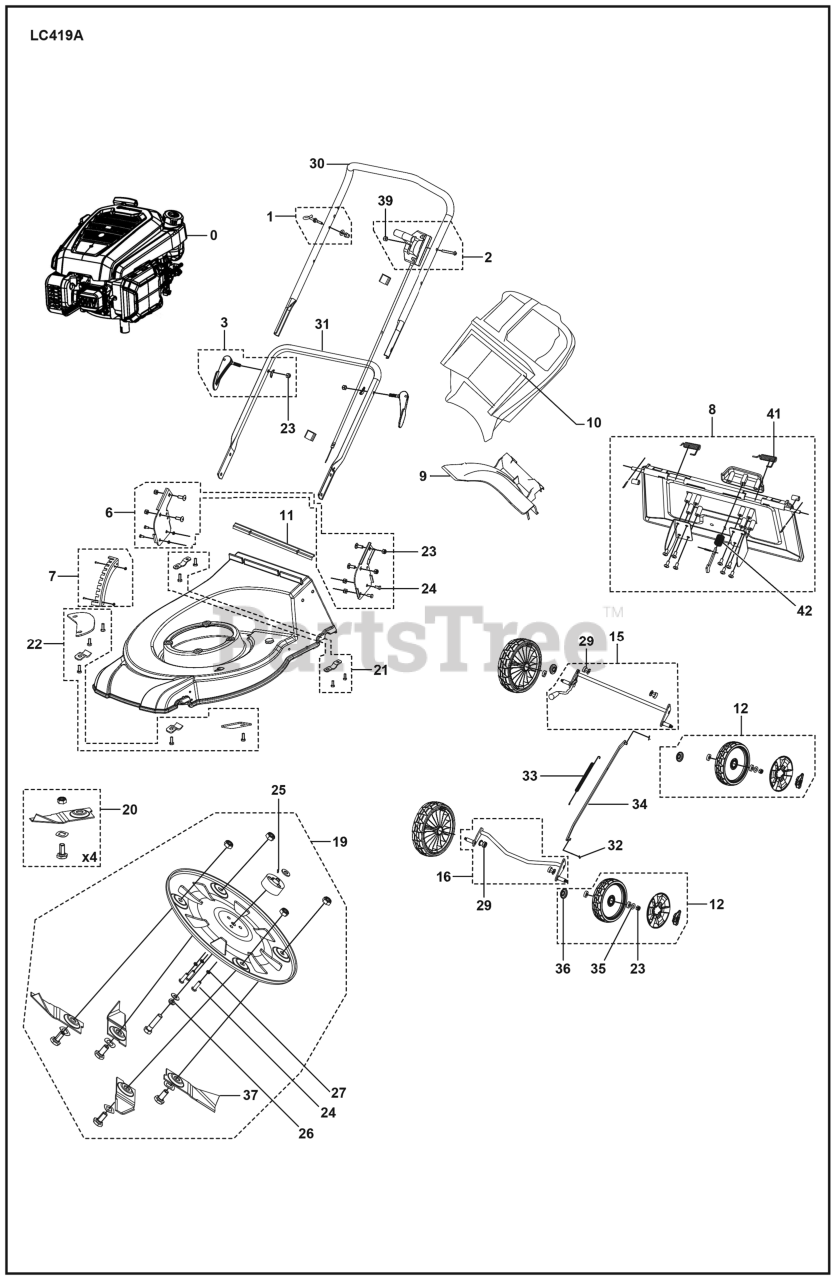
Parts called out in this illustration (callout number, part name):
23	LOCKNUT M8
26	Spring Washer
27	WASHER SPRING LOCK WASHER WITH
39	LOCKNUT M6
